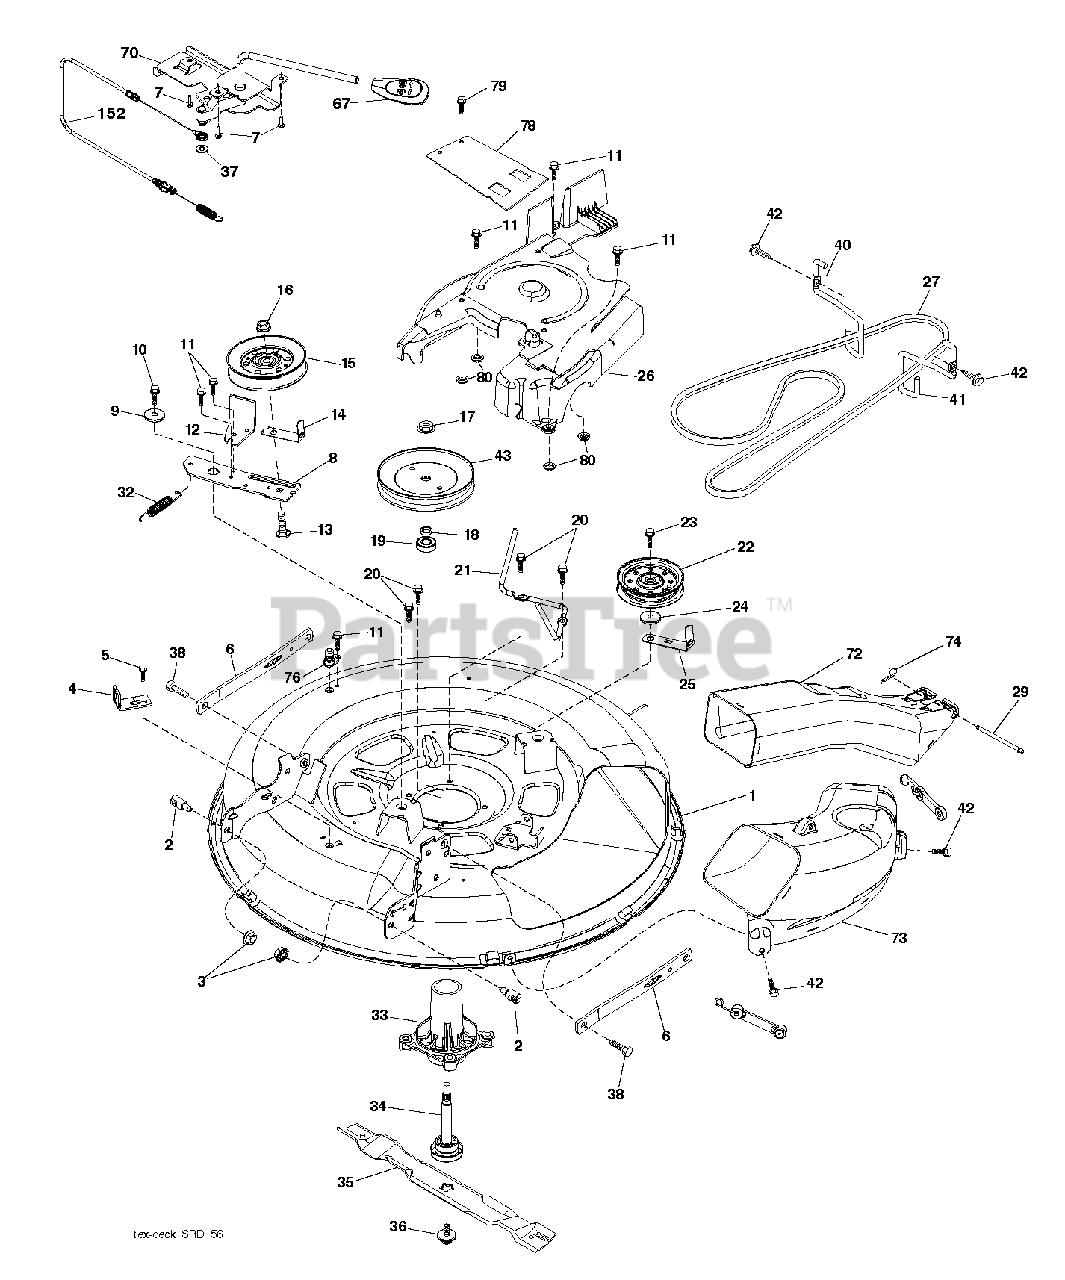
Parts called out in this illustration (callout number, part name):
2	STUD.FASTNER.W/ANTI-ROTATE
3	NUT LOCK HEX FLANGE 5/16-18
5	BOLT.5/16HEX.WHS.HD
6	ARMS.SUSP.MOWER.REAR.SRD
7	SCREW.#10 X 0.750.BOS THREAD
9	SPACER.RETAINER
10	SCREW 3/8-16X1
11	SCREW.1/4-20X5/8
12	ARM BRAKE MOWER RH
13	BOLT.3/8-16X1.50
14	KEEPER, BELT IDLER
15	PULLEY.IDLER.4.25
16	NUT LOCK FLG 3/8-16 UNC
17	NUT.FLANGE.LOCK.TOP
18	WASHER.SPACER.MANDREL
20	SCREW, WASHER HEAD
22	PULLEY.IDLER.FLAT.46.PR.DR.
23	SCREW LT
27	V-BELT.DRIVE.MOWER.30"
32	SPRING RETURN
33	HOUSING MANDREL
34	SHAFT.ASM.MDRL.N/GREASE.38
35	BLADE.MOWER.BAGGING.30"
36	BOLT.WASHER.ASM.7/16-2
38	BOLT.SHOULDER
42	SCREW, 3/8-16X3/4
43	PULLEY, MANDREL 6.5 PD
67	HANDLE.CLUTCH.CABLE.LT
70	CLUTCH.ASM.MANUAL.LT.PRED
74	RETAINER-SPRNG RB
76	PORT.WASHOUT
79	SCREW.HI-LO.CONSOLE
80	PALNUT 1/4
152	CABLE.CLUTCH.MANUAL.
